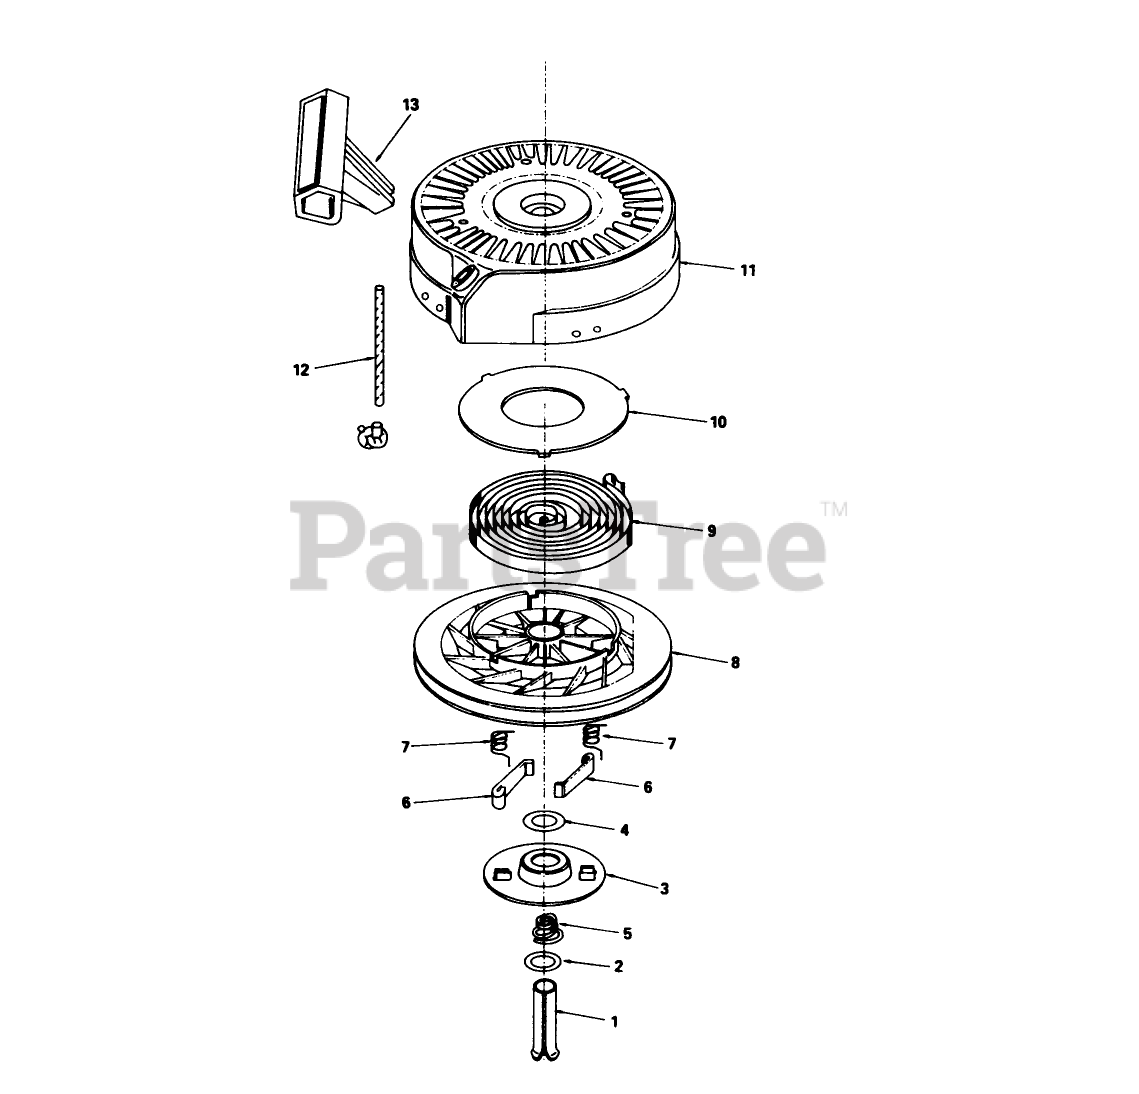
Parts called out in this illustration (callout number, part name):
1	Pin-Spring (Incl. Ref. #4)
3	Retainer
5	Brake Spring
6	Dog-Starter
7	Spring-Dog
8	Pulley
9	Rewind Spring
10	Cover-Spring
11	Housing-Starter
12	Rope-Starter (98 cut to length)
13	Handle-Starter
